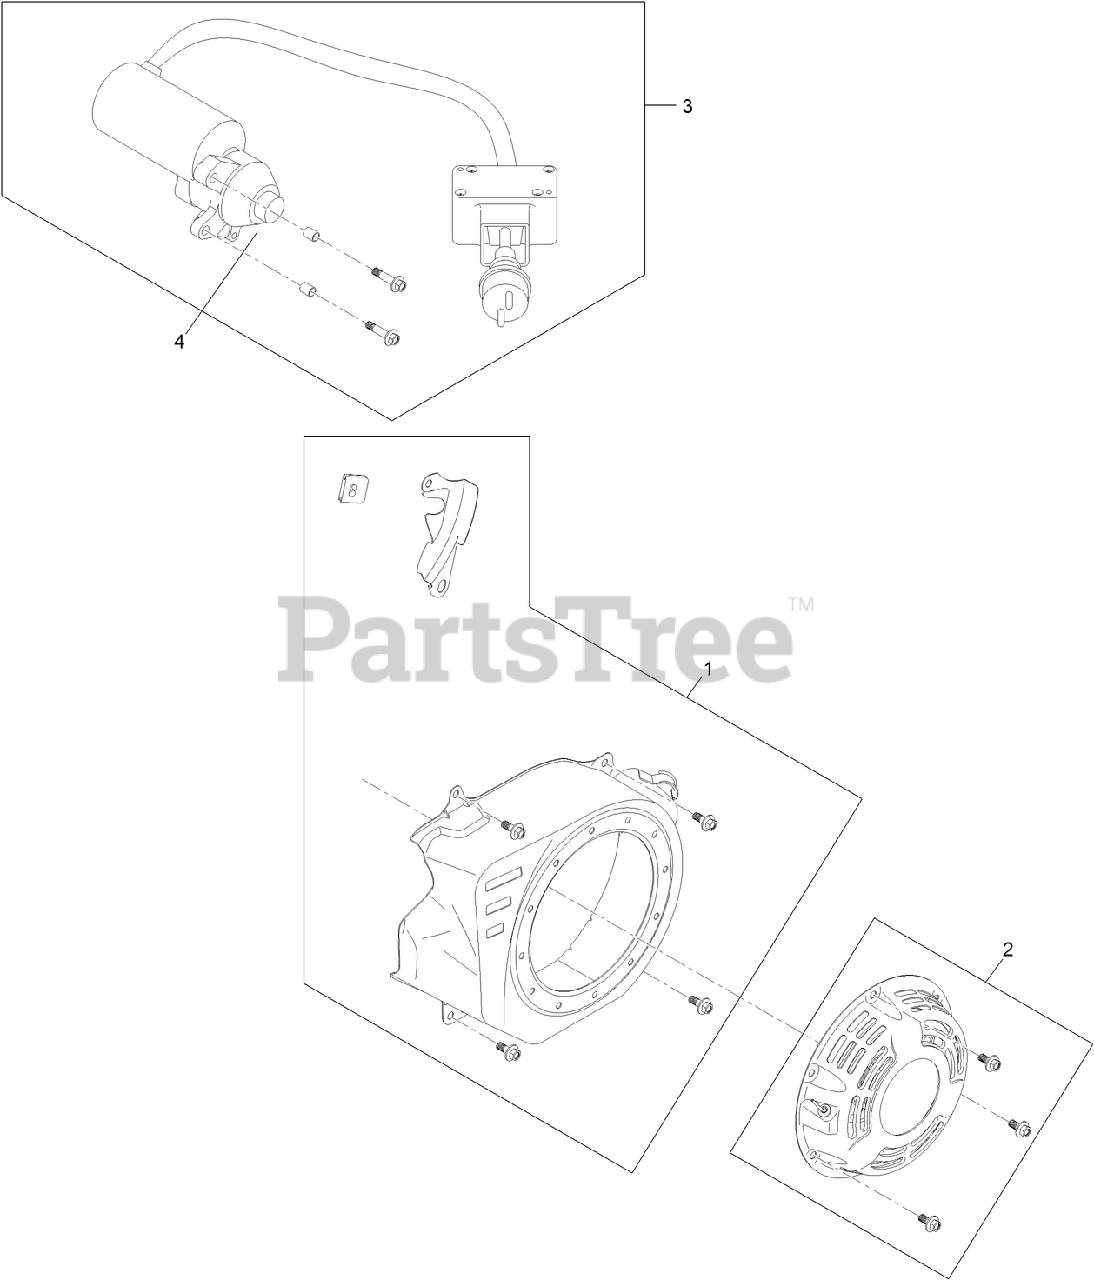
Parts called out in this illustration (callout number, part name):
1	BLOWER SHROUD KIT
2	RECOIL KIT
3	ELECTRIC STARTER KIT
4	PINION KIT
